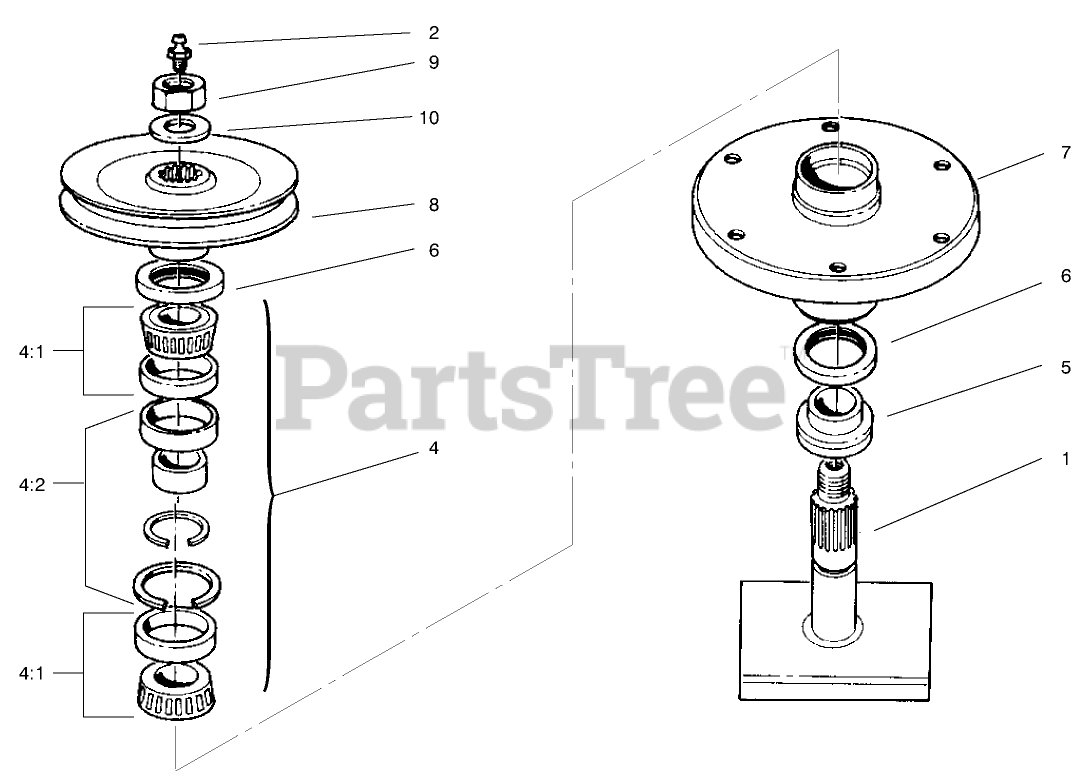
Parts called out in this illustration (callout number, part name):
1	SHAFT
2	FITTING-GREASE
4	BEARING ASM
4:1	BEARING ASM
4:2	SPACER-SET, MATCHED
5	SPACER
6	SEAL-OIL
7	HOUSING-SPINDLE
8	PULLEY AND HUB ASM
9	NUT-HEX
10	WASHER
